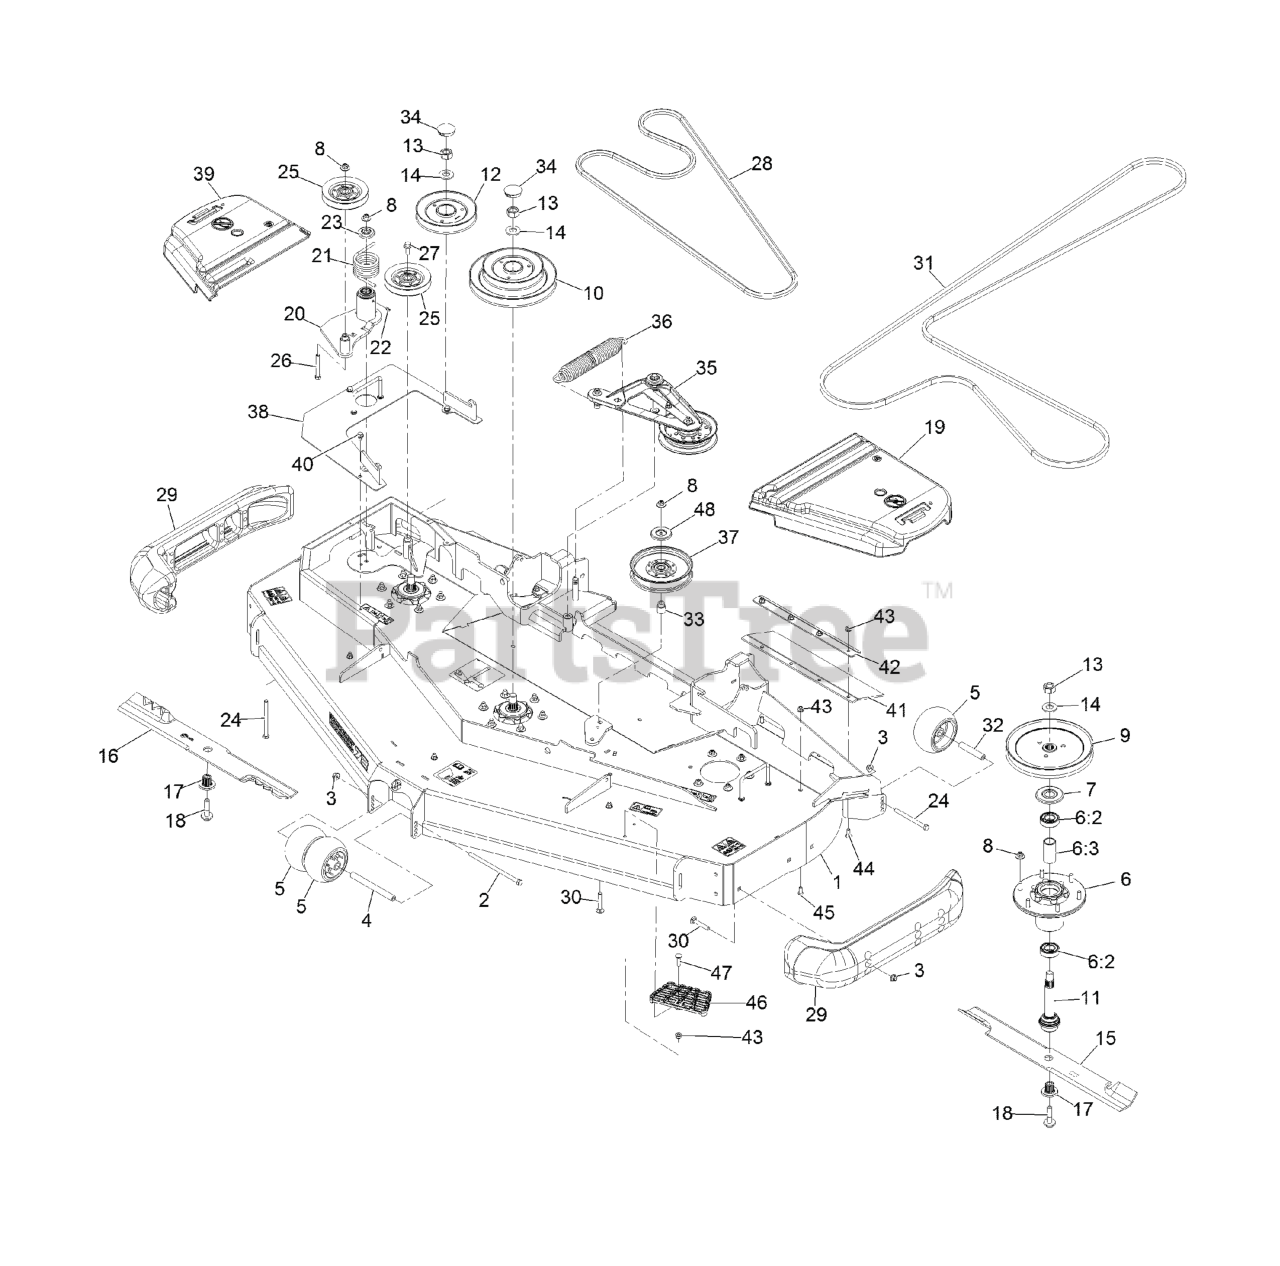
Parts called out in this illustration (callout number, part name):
1	DECK-RD72 NLZ, W/DECALS
2	SCREW-HH
3	NUT-HF, NI
4	SPACER-WHEEL
5	ROLLER-SCALP, ANTI
6	ASM-CUTTER HSG WITH BEARINGS
6:2	BEARING-BALL
6:3	SPACER-BEARING
7	GUARD,BEARING TOP .989
8	Nut-Nyloc 3/8-16 Flg
9	SHEAVE,BLADE DRIVE 8.74
10	SHEAVE, DOUBLE 72RD
11	ASM-SPINDLE AND SEAL
12	SHEAVE-RD REV DRIVE SERIES 4
13	NUT-HEX
17	BUSHING,SPLINED
18	SCREW,SEMS 1/2-20 X 2.19
19	COVER-BELT, LH
20	IDLER ASM
21	SPRING-TORSION
22	FITTING-GREASE
23	GUARD-TOP
24	SCREW-HH
26	SCREW-HH
27	SCREW-HHF
29	SKID-BUMPER, DECK
30	Bolt-Carriage 3/8-16 X 2 1/4
31	BELT
32	TUBE-SPANNER
33	BUSHING-IDLER
34	PLUG,BLACK NYLON 1.75
35	DECK IDLER ASM
36	SPRING-EXTENSION
37	IDLER-PULLEY, FLAT 6.00X1.00
38	COVER-REVERSE DRIVE
39	COVER-BELT, RH
41	GUARD-TIRE
42	SUPPORT-OUTER FLAP
43	NUT-HF, NI
44	SCREW-CARR
45	SCREW-HSBH
46	STEP-DECK
47	Bolt-Carriage 5/16-18 X 1 1/4
48	SHIELD-DUST
